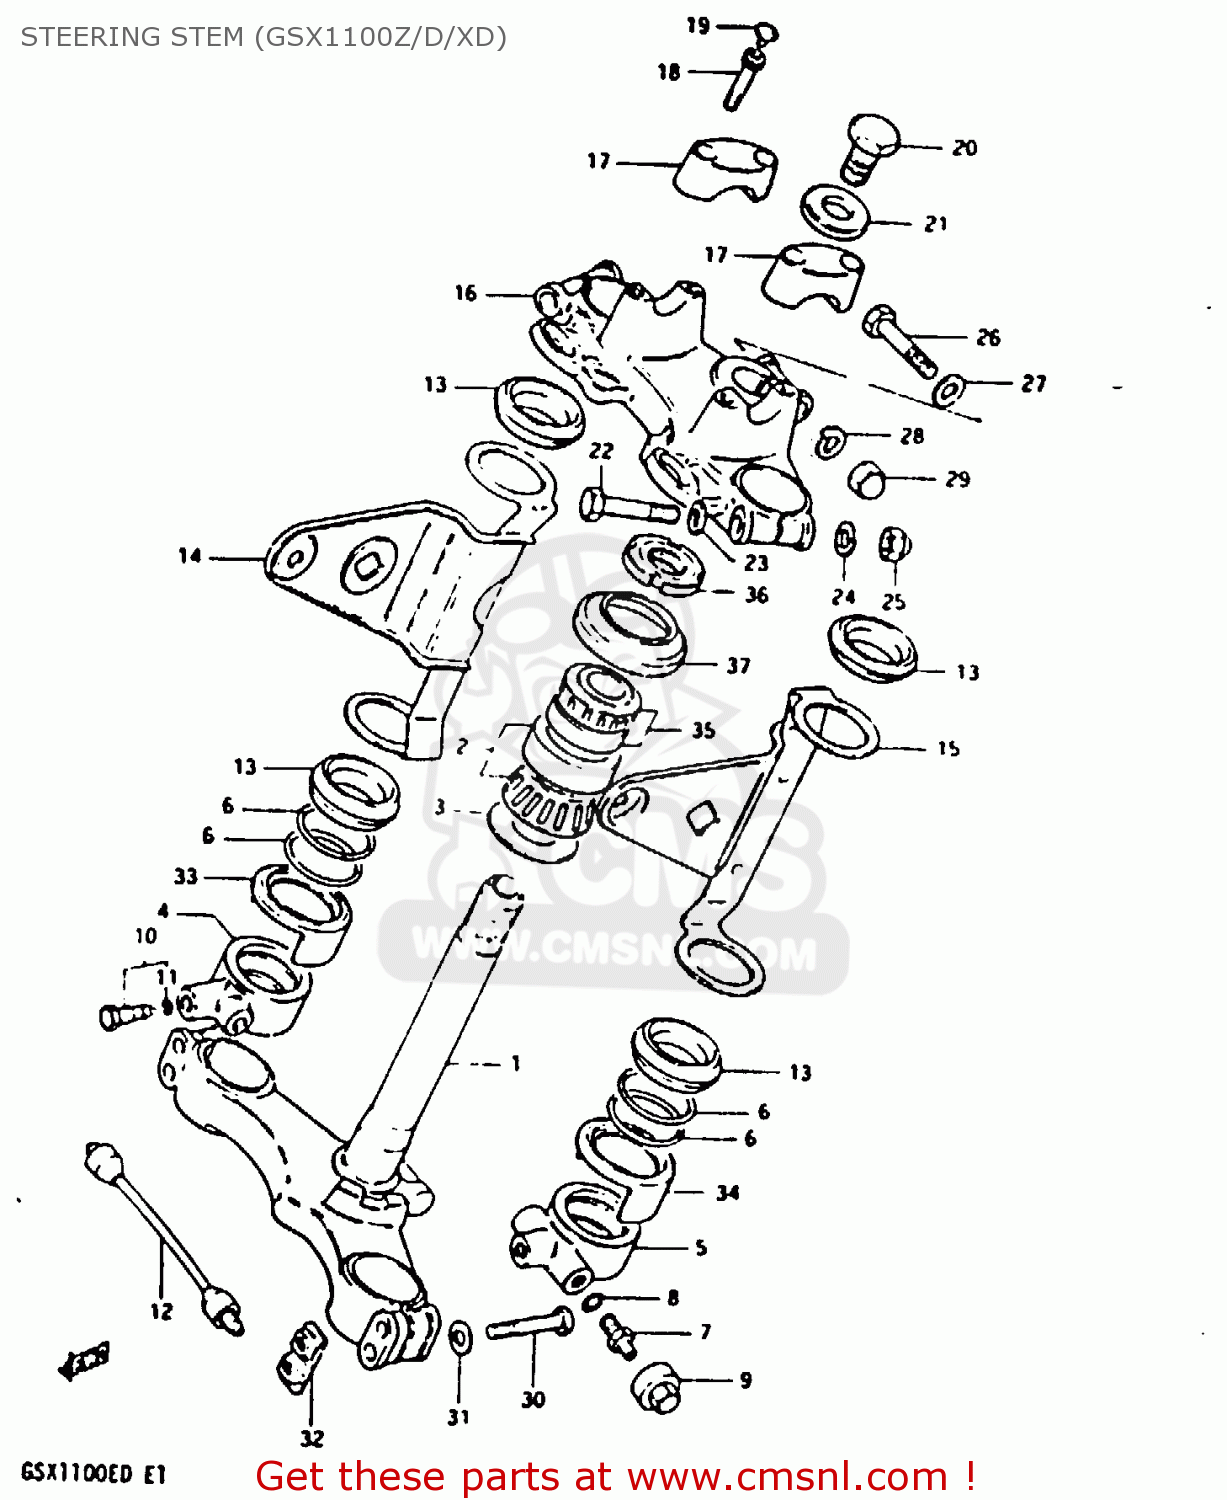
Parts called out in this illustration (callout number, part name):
1	STEM,STEERING
2	BEARING
3	WASHER,THRUST
4	JOINT,AIR,RIGHT
5	BRACKET,FORK CONNECTING
6	O RING
7	VALVE
8	O RING
9	CAP,VALVE
10	VALVE,STOP
11	O RING
12	HOSE,FORK CONNECTING
13	CUSHION,HEADLAMP BRACKET
14	BRACKET,HEADLAMP,RIGHT
15	BRACKET,HEADLAMP,LEFT
16	HEAD,STEERING STEM
17	HOLDER,HANDLEBAR
18	BOLT
19	CAP(OD:14.5)
20	NUT,STEM HEAD
21	WASHER,STEERING STEM B
22	BOLT 10X55
23	WASHER
24	LOCK WASHER
25	NUT 10MM
26	BOLT 8X50
27	WASHER
28	LOCK WASHER
29	NUT,M8X1.25X12
30	BOLT 8X55
31	WASHER
32	NUT,FR FORK INNER TUBE
33	COVER,FORK BRACKET,RIGHT
34	COVER,FORK BRACKET,LEFT
35	TAPER,ROLLER BEARING
36	NUT,STEERING STEM
37	DUST SEAL,STEERING UPR
